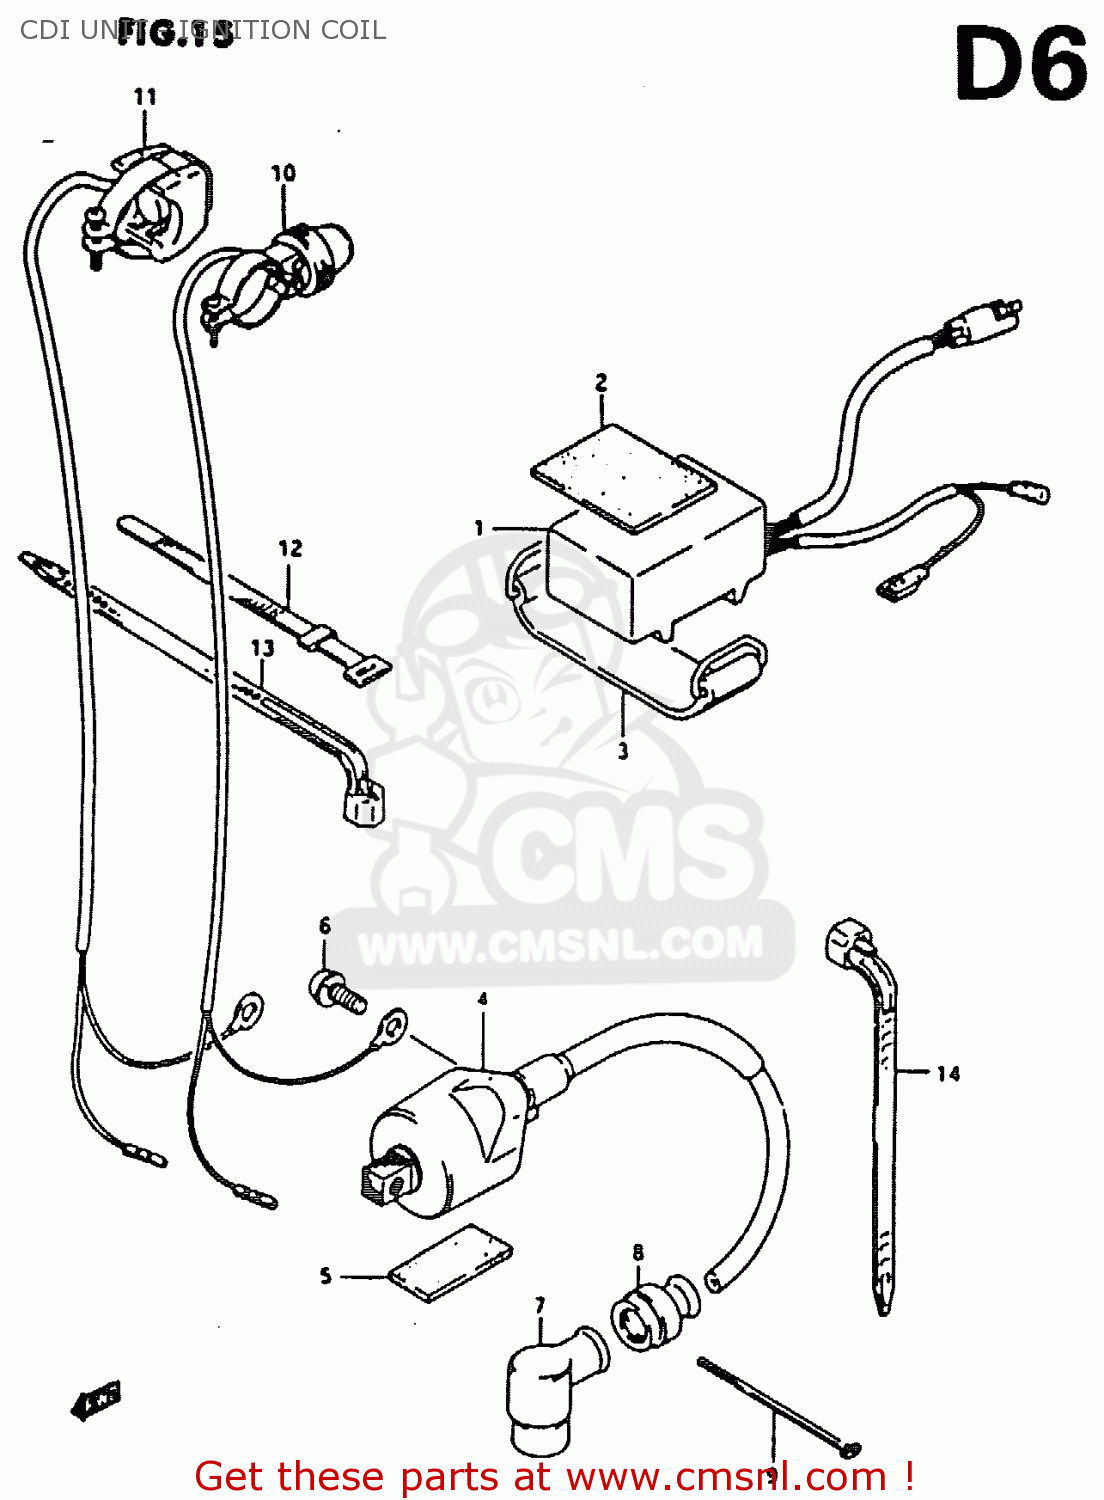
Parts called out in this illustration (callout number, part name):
1	CDI UNIT
2	PROTECTOR(170X95X3.0)
3	BAND
4	COIL ASSY,IGNITION
5	PROTECTOR(170X95X3.0)
6	SCREW
7	CAP,SPARK PLUG
8	SEAL,HIGH TENSION CORD
9	CLAMP
10	SWITCH ASSEMBLY
11	SWITCH ASSY,ENGINE STOP
12	CLAMP(L:120)
13	CLAMP L:165
14	CLAMP(L:125)
